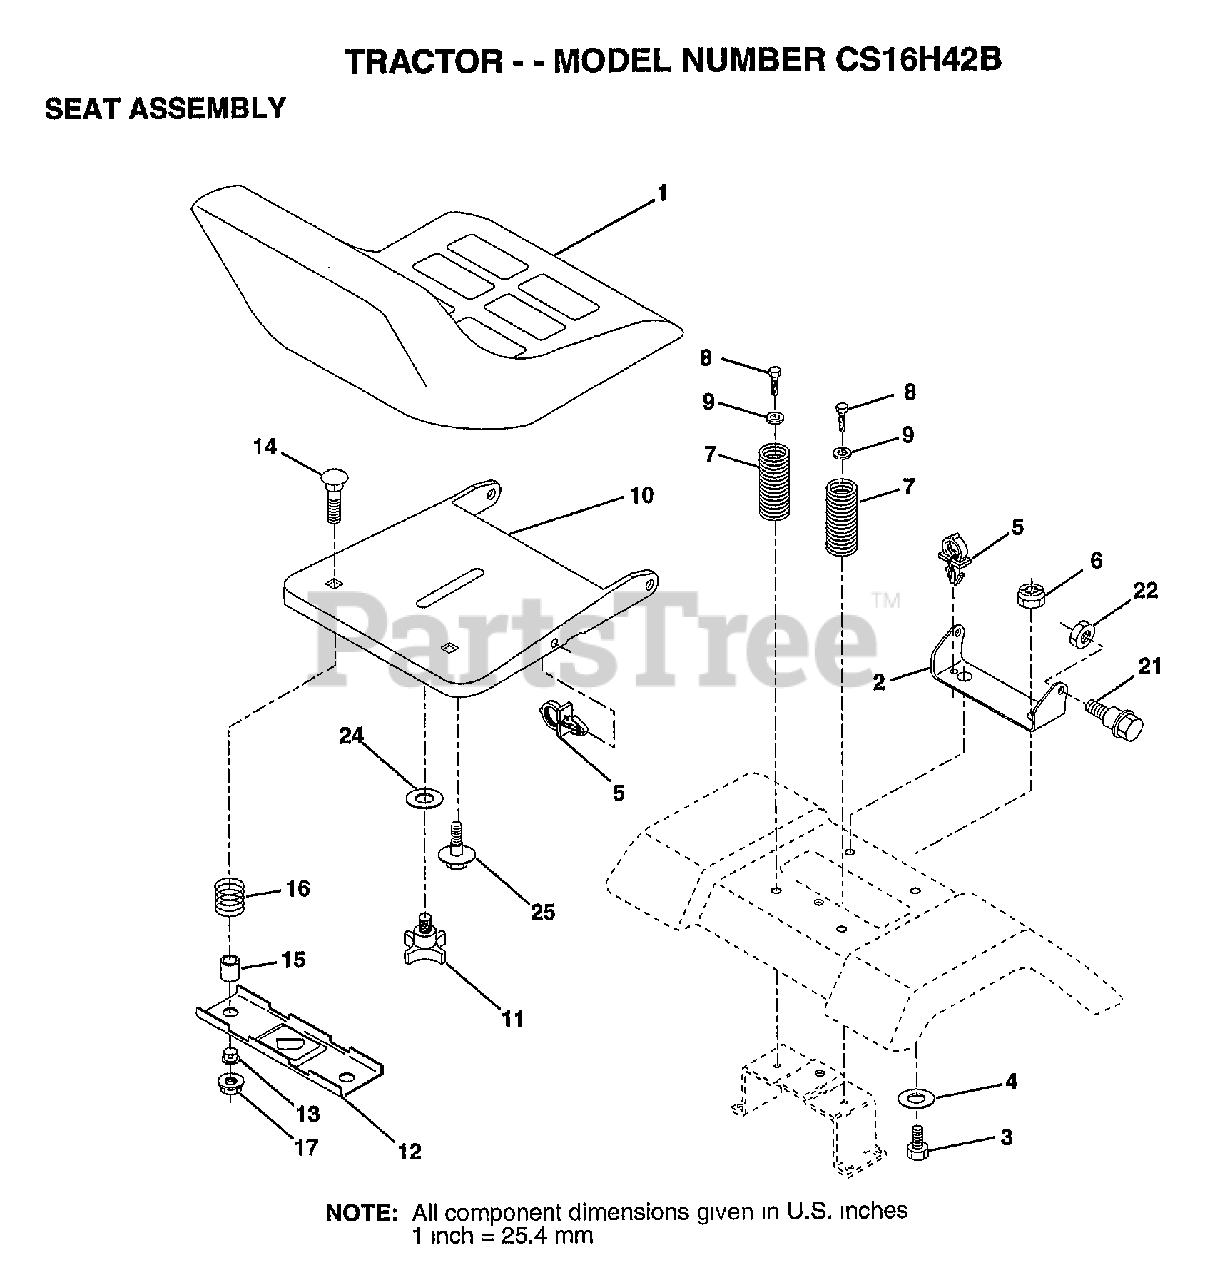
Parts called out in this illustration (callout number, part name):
2	BRACKET PVT SEAT
3	BOLT
4	WASHER PM
5	CLIP.PUSH-IN.HING
6	NUT
7	SPRING COMPRESSIO
8	SCREW GTV
9	WASHER
10	PAN-SEAT
11	"KNOB 1/2"" YT"
12	BRKT SWITCH
13	BUSHING
15	SPLIT SPACER
16	SPRING
21	"BOLT,SHOULDER"
22	NUT
24	WASHER
25	"BOLT,SHOULDER"
26	LOCKWASHER
